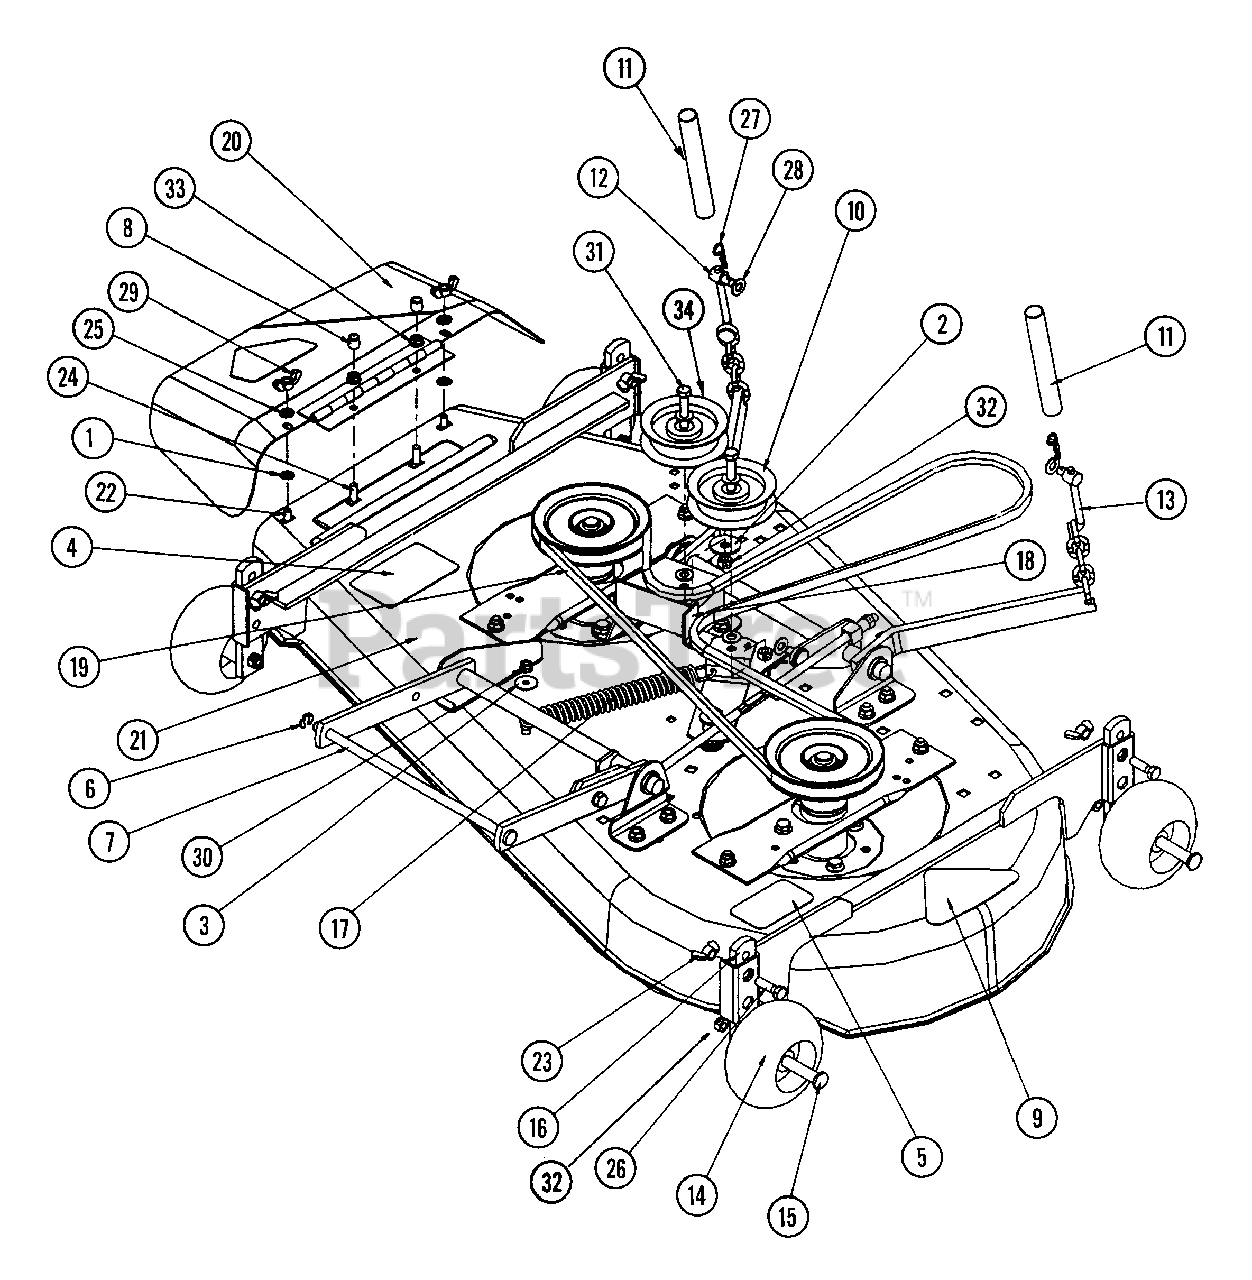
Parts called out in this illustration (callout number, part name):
1	RETAINER, 5/16 Bolt
2	WASHER, Cone
3	WASHER, 1/4" I.D.x 1" O.D.
4	DECAL, CAUTION
5	DECAL, CAUTION
6	RING, 7/16" Snap
7	ROD, Deck Support
8	CAP, Vinyl
9	DECAL, 42 Inch
10	IDLER, 4" Outside Diameter, Flat
11	CHAIN, Cover
12	SWIVEL, Adjustable
13	ADJUSTER, Chain
14	WHEEL, Gauge
15	BOLT, 3/8-16 x 3-3/8" Gauge Wheel
16	POST, Anti-Scalp
17	SPRING, External
18	GUIDE, 38"/42" Idler Belt
19	BELT, 42"
20	ASSEMBLY, 41" Chute
21	DECK, 42" Painted
22	BOLT, 5/16-18 x 5/8" Short Neck Carriage, Grade 5
23	NUT, 3/8-16 Wing, Nylon Ring
24	BOLT, 5/16-18 x1" Short Neck Carriage, Grade 5
25	WASHER, 5/16" Split Lock
26	SCREW, 3/8-16 x 1-1/4" Hex Head Cap, Grade 5
27	HAIRPIN, 3/32 x 1-1/2"
28	WASHER, 3/8" Flat
29	NUT, 5/16-18 Wing Lock
30	NUT, 1/4-20 Hex Flange Lock
31	SCREW, 3/8-16 x 1-3/4" Hex Head Cap
32	NUT, 3/8-16 Hex Lock
33	NUT, 5/16-18 Flange Lock
34	PULLEY
